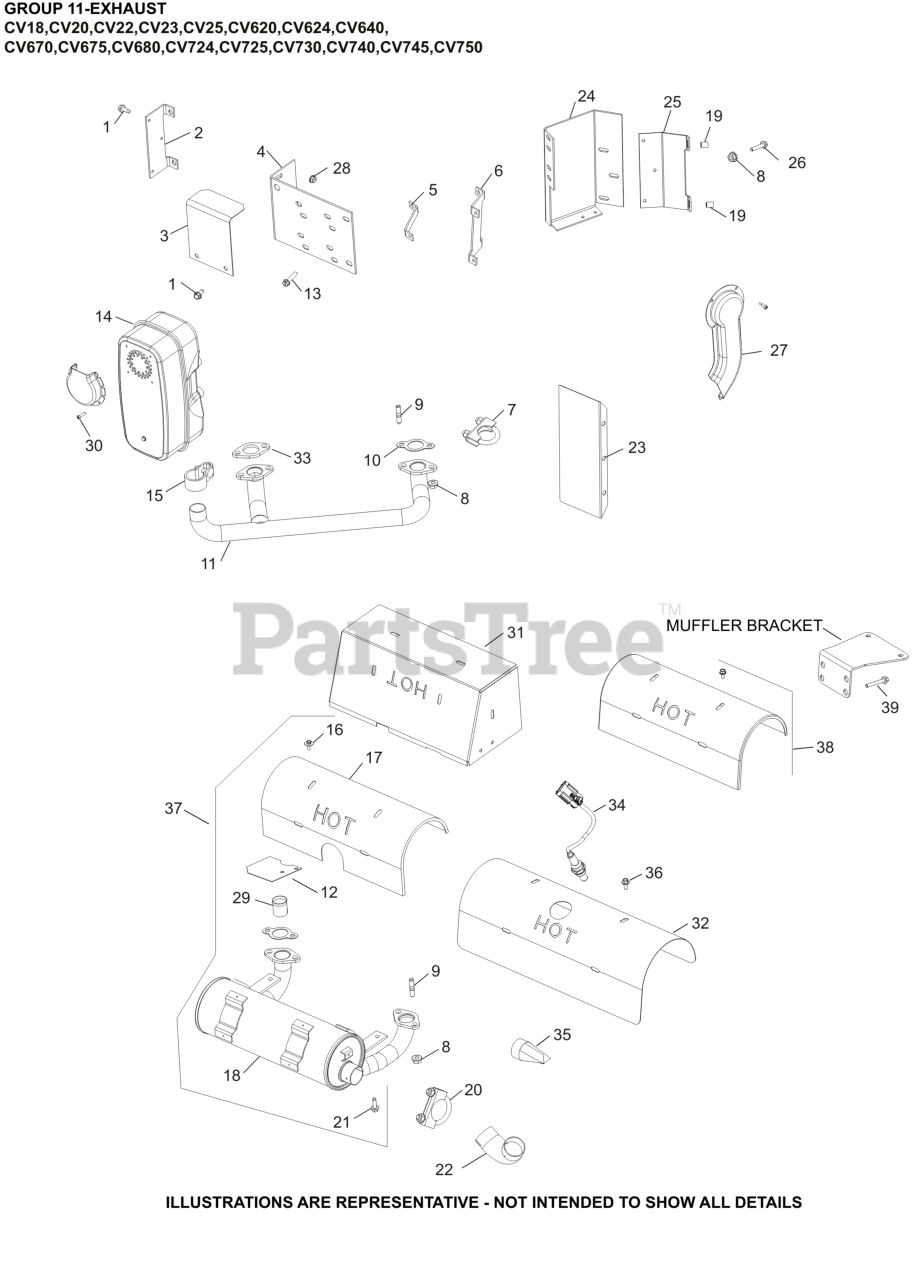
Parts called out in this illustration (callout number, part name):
3	DEFLECTOR, HEAT
8	NUT, FLG M8X1.25
9	STUD, M6X1.0X36
9	STUD, METRIC EXHAUST
10	GASKET, EXHAUST
28	NUT, FLG M6X1.0
